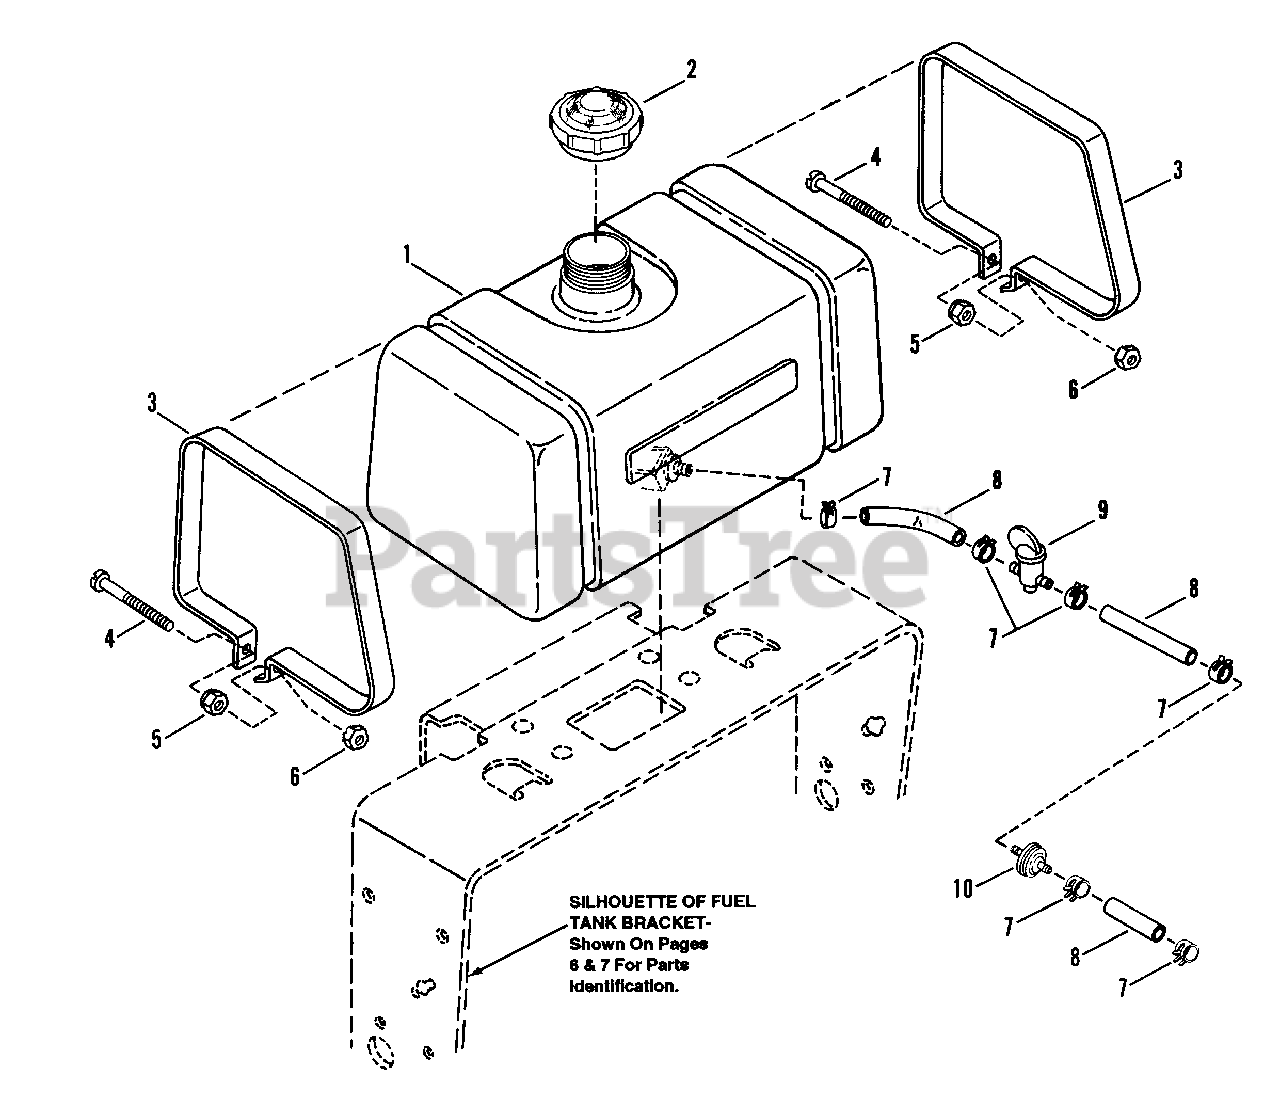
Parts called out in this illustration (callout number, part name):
1	TANK, Fuel
2	CAP, Fuel
3	STRAP, Fuel Tank
4	SCREW, #10-24 x 2-1/2" Machine Head Phillips
5	NUT, #10-24 Keps
6	NUT, #10-24 Nyloc
7	CLAMP, Fuel Hose
8	HOSE, Fuel, 10" Long
9	VALVE, Fuel Shut-Off
10	FILTER, Fuel, In-Line
